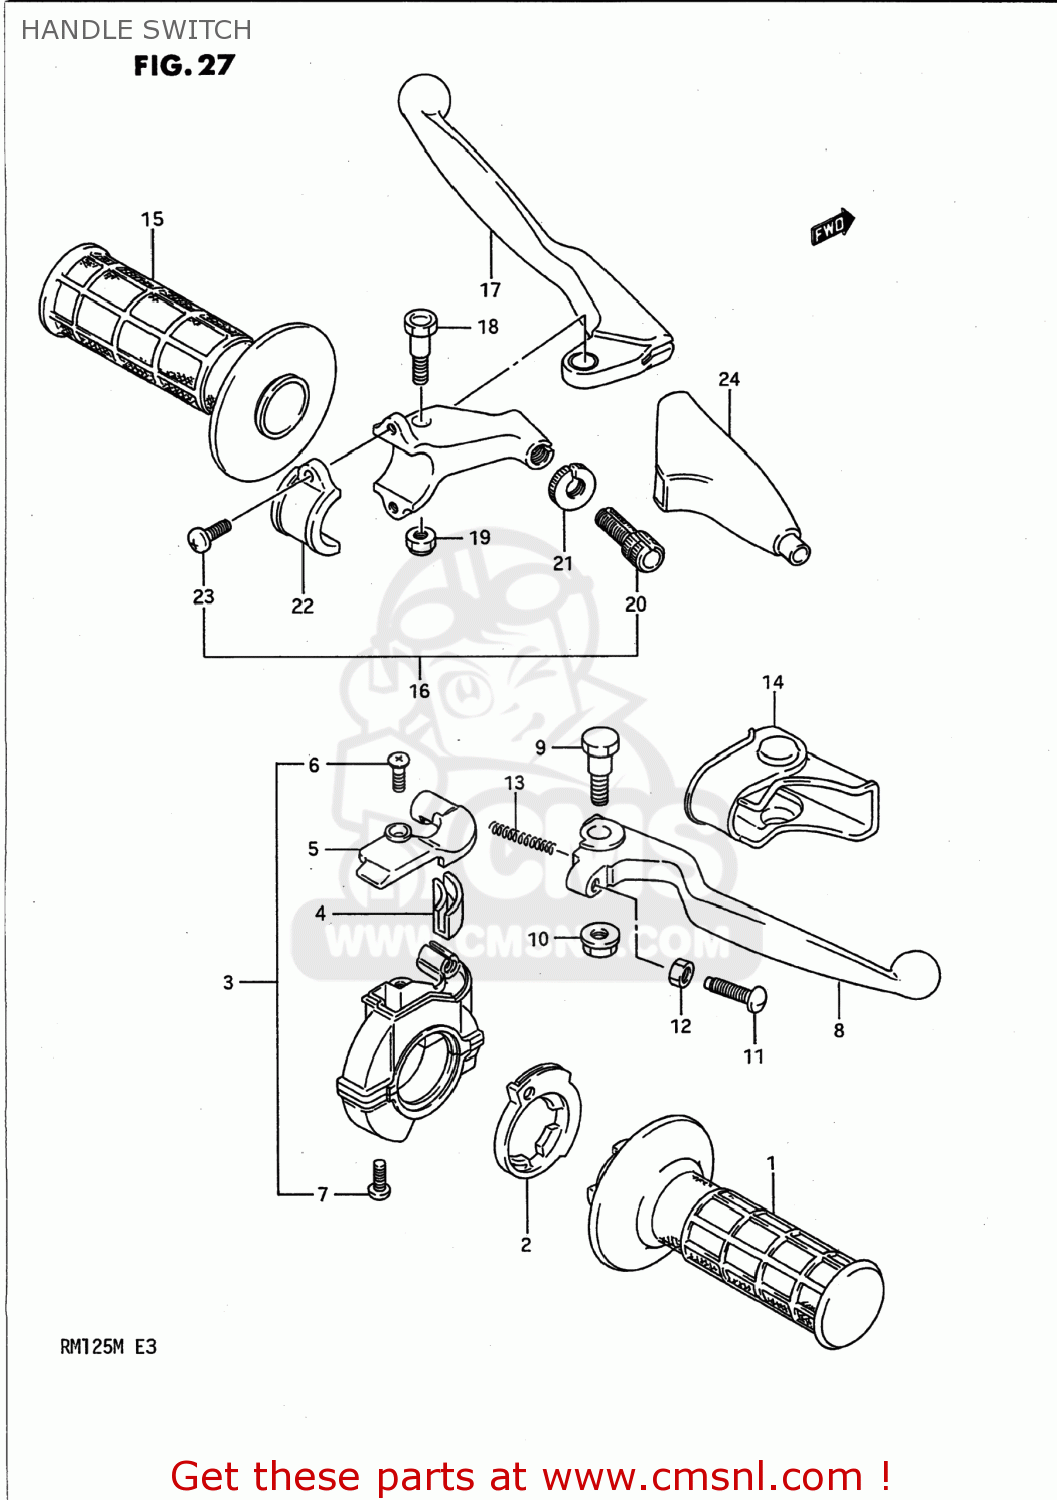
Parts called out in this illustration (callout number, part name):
1	GRIP,THROTTLE
2	ROTOR,THROTTLE GRIP
3	CASE ASSY,THROTTLE
4	GUIDE PIECE,THROTTLE
5	COVER,THROTTLE CASE
6	SCREW 4X10
7	SCREW
8	LEVER,BRAKE
9	BOLT,BRAKE LEVER
10	NUT,BRAKE LEVER
11	BOLT,ADJUST
12	NUT ,5MM
13	SPRING,RETURN
14	COVER,BRAKE LEVER
15	GRIP,L
16	LEVER ASSY,CLUTCH
17	LEVER,CLUTCH
18	BOLT,LEVER
19	NUT 6MM
20	ADJUSTER,CABLE
21	NUT,CABLE ADJUSTER
22	BRACKET,CLUTCH LEVER HOLDER
23	SCREW(5X14)
24	COVER,CLUTCH LEVER
